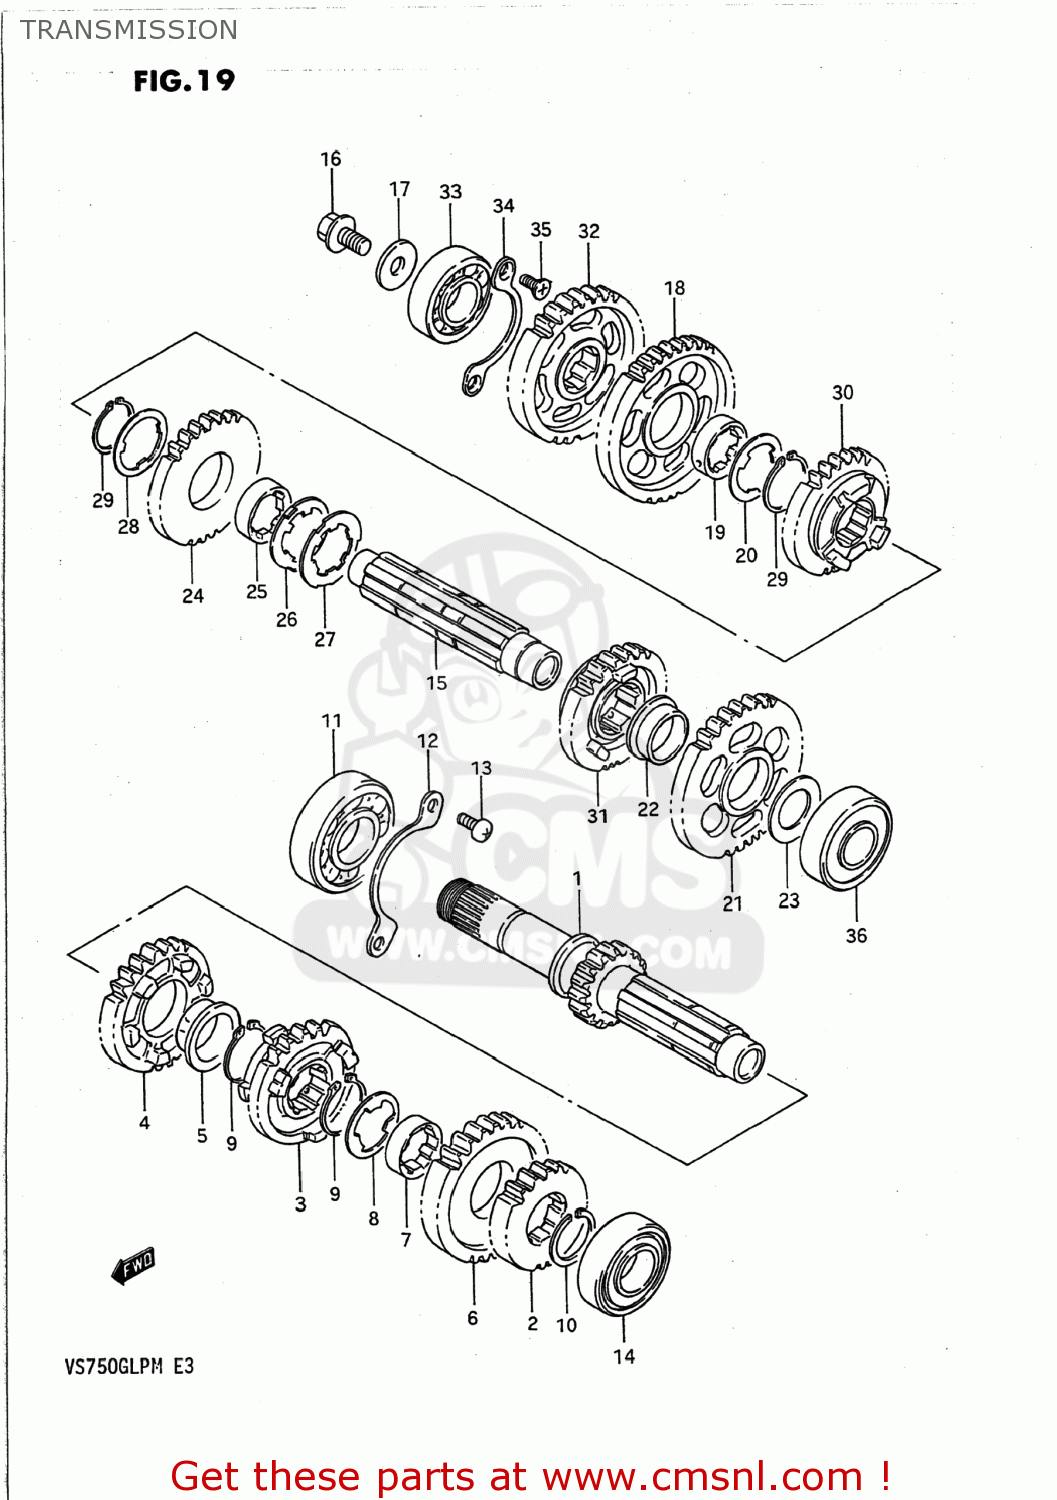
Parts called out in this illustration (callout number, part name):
1	COUNTER SHAFT
2	GEAR,2ND DRIVE(NT:19)
3	GEAR,THIRD DRIVE
4	GEAR,4TH DRIVE(NT:25)
5	BUSHING
6	GEAR,FIFTH DRIVE (NT:27)
7	BUSHING
8	WASHER,LOCK
9	RING,SNAP
10	CIRCLIP
11	BEARING(25X62X17)
12	RETAINER,CNTR SHAFT BEARING
13	SCREW
14	BEARING 20X47X14
15	SHAFT,DRIVE
16	NOZZLE,DRIVE SHAFT
17	WASHER
18	GEAR,FIRST DRIVEN (NT:32)
19	BUSH
20	WASHER,LOCK
21	GEAR,2ND DRIVEN(NT:31)
22	BUSH
23	WASHER
24	GEAR,3RD DRIVEN(NT:27)
25	BUSH
26	WASHER
27	WASHER,LOCK
28	WASHER,LOCK
29	CIRCLIP
30	GEAR,FOURTH DRIVEN
31	GEAR,FIFTH DRIVEN
32	GEAR,REDUCTION DRIVE(NT:30)
33	BEARING(20X52X15)
34	RETAINER,DRIVE SHAFT BEARING
35	SCREW
36	BEARING(20X52X15)
